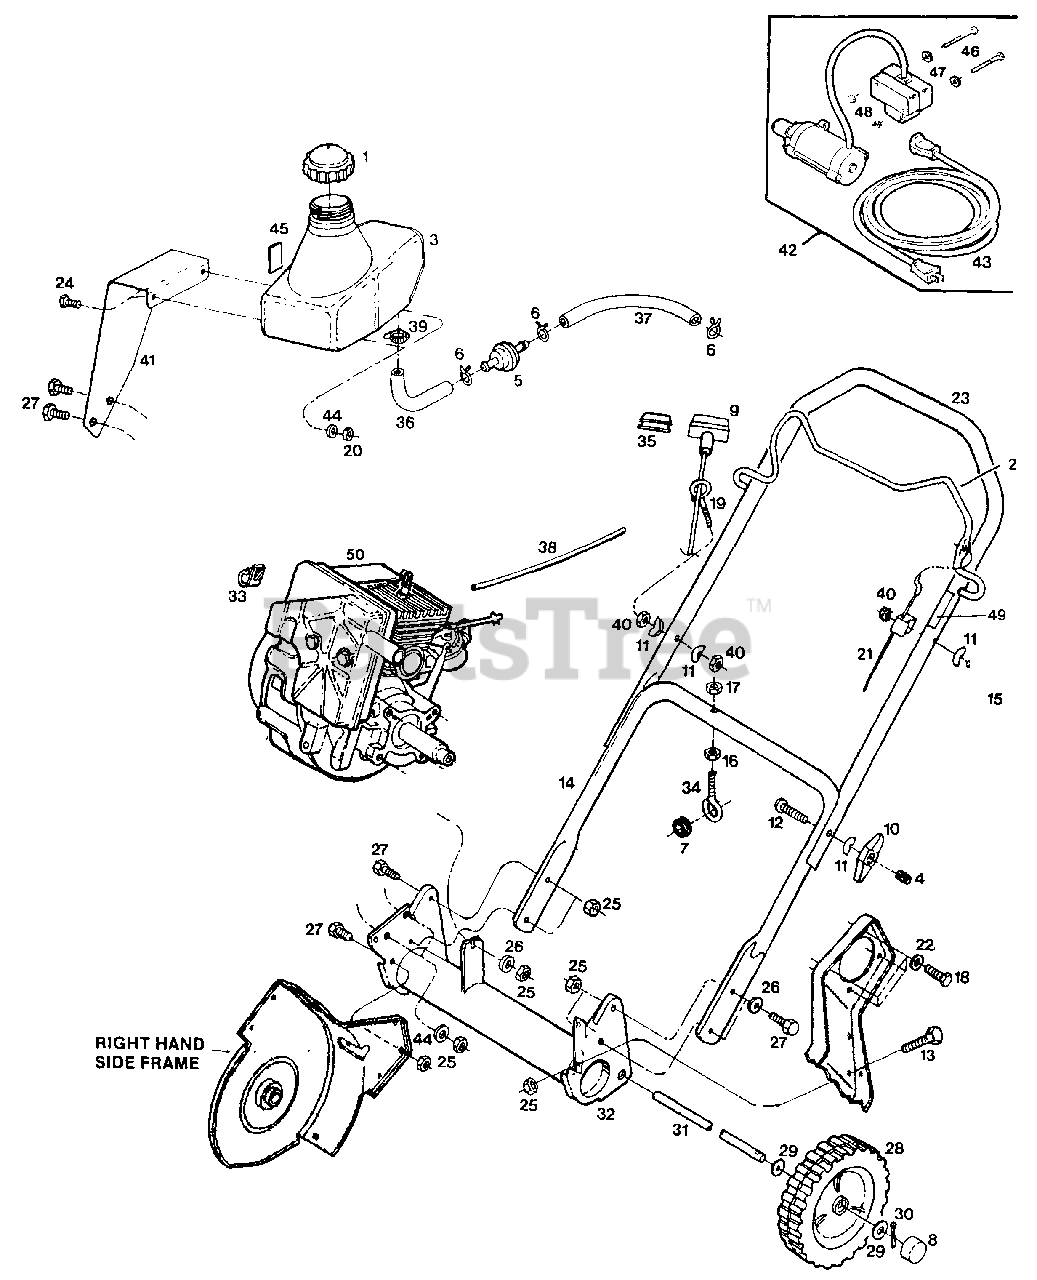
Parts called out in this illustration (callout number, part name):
1	CAP - Tank
2	BAIL - Auger Control
3	TANK - Fuel
4	CAP - Plastic Bolt
5	FILTER - Gas
6	CLAMP - Wireform
7	GROMMET - Eyebolt
8	CAP - Hub
9	HANDLE - Starter Rope
10	KNOB - Wing
11	WASHER - Curved 5/16
12	BOLT - Curved Head 5/16 - 18 x 2-14
13	BOLT - Hex 5/16 - 18 x 1
14	HANDLE - Lower
15	BOLT - Hex 1/4 - 20 x 2
16	NUT - Hex 3/8 - 16
17	NUT - Flange Lock 3/8 - 16
18	BOLT - Hex 5/16 - 18 x 5/8
19	GUIDE - Rope
20	NUT - Nylock 1/4 - 20
21	CABLE - Auger Control
22	WASHER - Lock 5/16
23	HANDLE - Upper
24	BOLT - Hex 1/4 - 20 x 3/4
25	NUT, 5/16-18 Nylock
26	WASHER - Flat 5/16 (Left Side Only)
27	BOLT - Hex 5/16 - 18 x 3/4
28	WHEEL & TIRE
29	WASHER - Flat
30	PIN - Cotter 1/8 x 3/4
31	SHAFT - Axle
32	FRAME - Tube
33	CLIP - Retainer
34	EYEBOLT - Chute Rotate
35	INSERT - Metal Handle
36	HOSE - Fuel 3-1/4" Lg.
37	HOSE - Fuel 6" Lg.
38	HOSE - Fuel 7-1/2" Lg., Primer
39	CLAMP - Wormdrive
40	NUT - Keps 1/4 - 20
41	BRACKET - Fuel Tank
42	KIT - Electric Start
43	CORD - Extension 10'
44	WASHER - Flat 1/4
45	PAD - Rubber
46	SCREW #6 - 32 x 2-1/2 H.H.
48	NUT #6 - 32 Keps
49	DECAL - Auger Control
50	ENGINE, 5 HP Two Cycle
